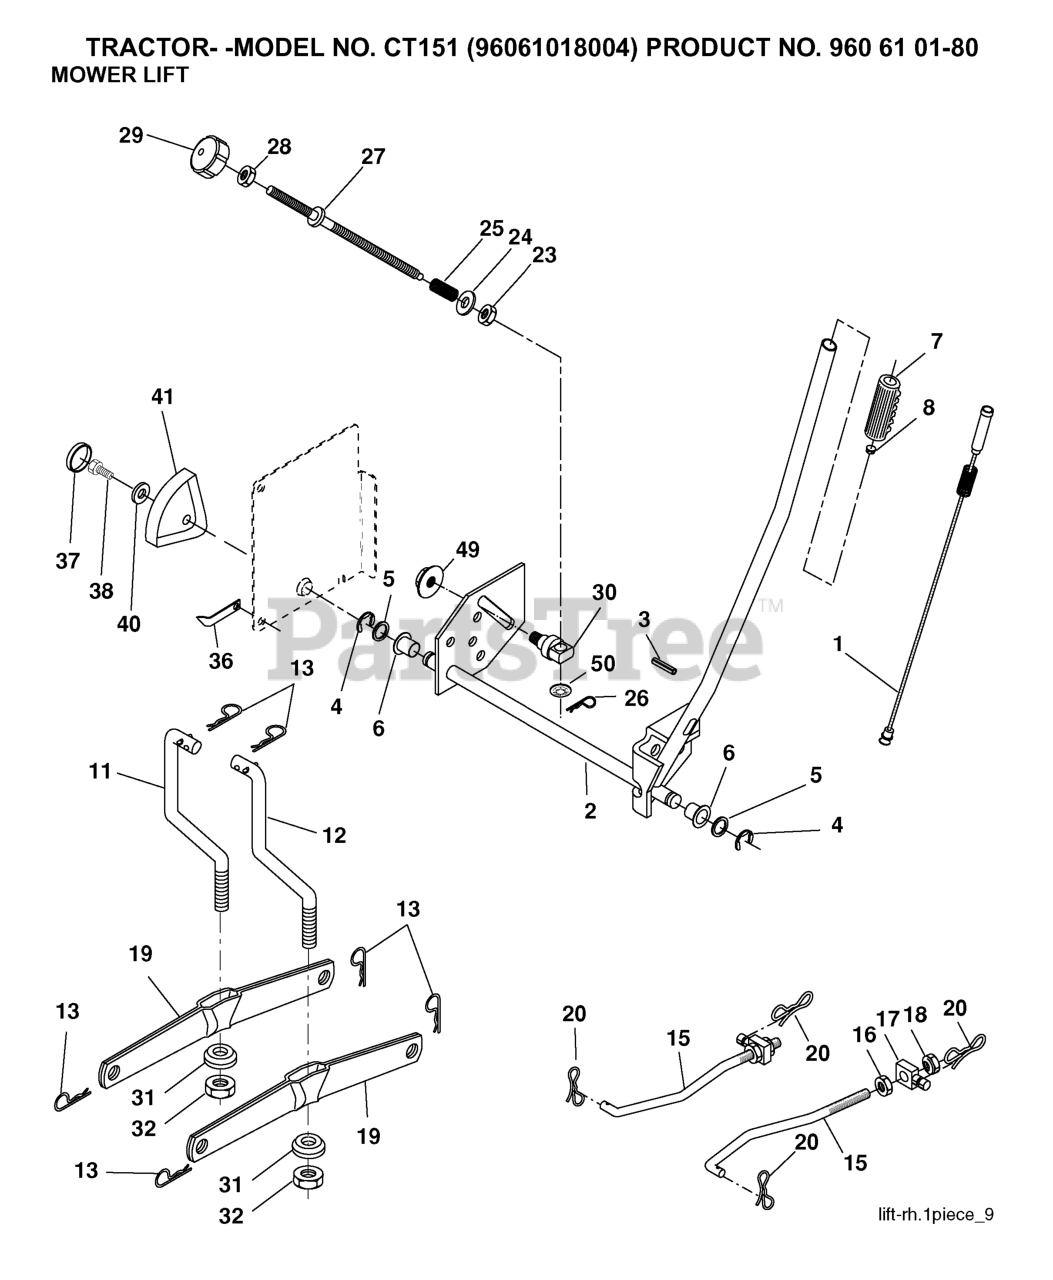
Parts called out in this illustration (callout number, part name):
1	WIRE ASM INNER W/ PLUNGER LT
2	SHAFT ASM R HANDLE
3	PIN GROOVE.
4	RETAINING RING LT
6	BEARING.NYLON
7	GRIP HANDLE
8	REPL BY 532 12 59-25
11	LINK
12	LINK
13	RETAINER-SPRNG RB
15	LINK.SUSPENSION.FRONT
16	NUT.HEX.JAM.1/2-13
18	NUT.LK.W/WSH.1/2.
19	ARM.REAR.SUSPENSION
20	PIN.COTTER.7/16.BOW TI.
26	RETAINER CLIP
27	ROD ADJ LIFT
28	NUT
29	KNOB INF 3/8-16
31	BEARING.PIVOT.LIFT
32	NUT CROWNLOCK 3/8-24
36	POINTER, HEIGHT INDICATOR(2 2)
38	SCREW 5/16-18X1
41	HEIGHT INDICATOR
49	NUT
50	NUT PUSH M
